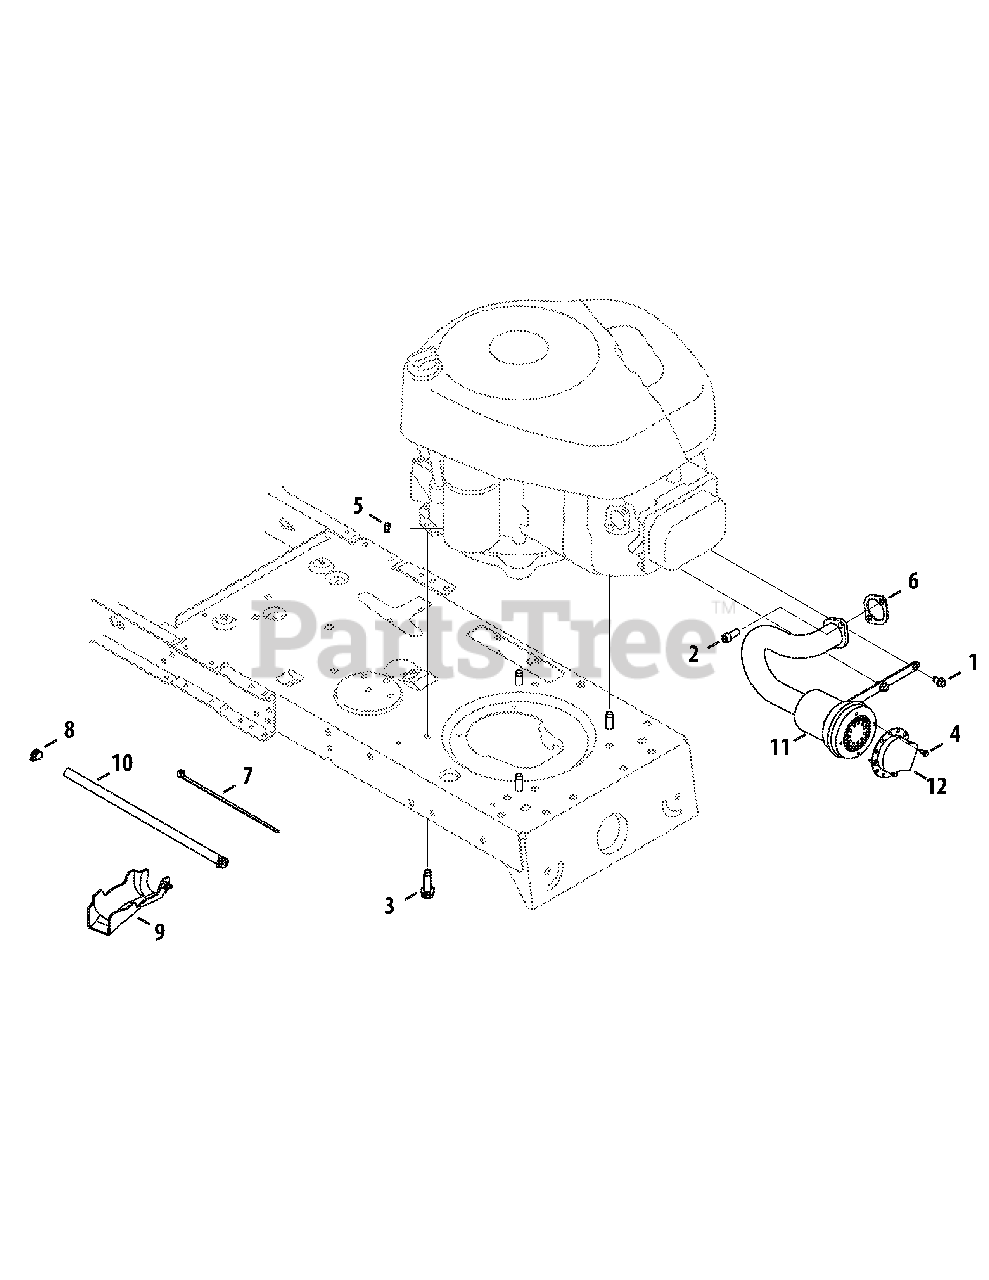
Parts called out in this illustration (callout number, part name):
1	Screw, ab, #8-18, 0.500
2	Tap Screw, 3/8-16, 1.000
3	Tap Screw, 1/4-20, 0.500
4	Screw, Socket Head, 5/16-18, .750
5	Sems Nut, 1/4-20
6	Exhaust Gasket, 10 HP B&S #272293
7	Cable Tie, 3/16 X .05 X 7.4
8	Hose Clamp, .490 Dia.
9	Oil Drain Sleeve
10	Hose, fuel, low Permeation, 1/4
11	Muffler
12	Muffler Deflector
